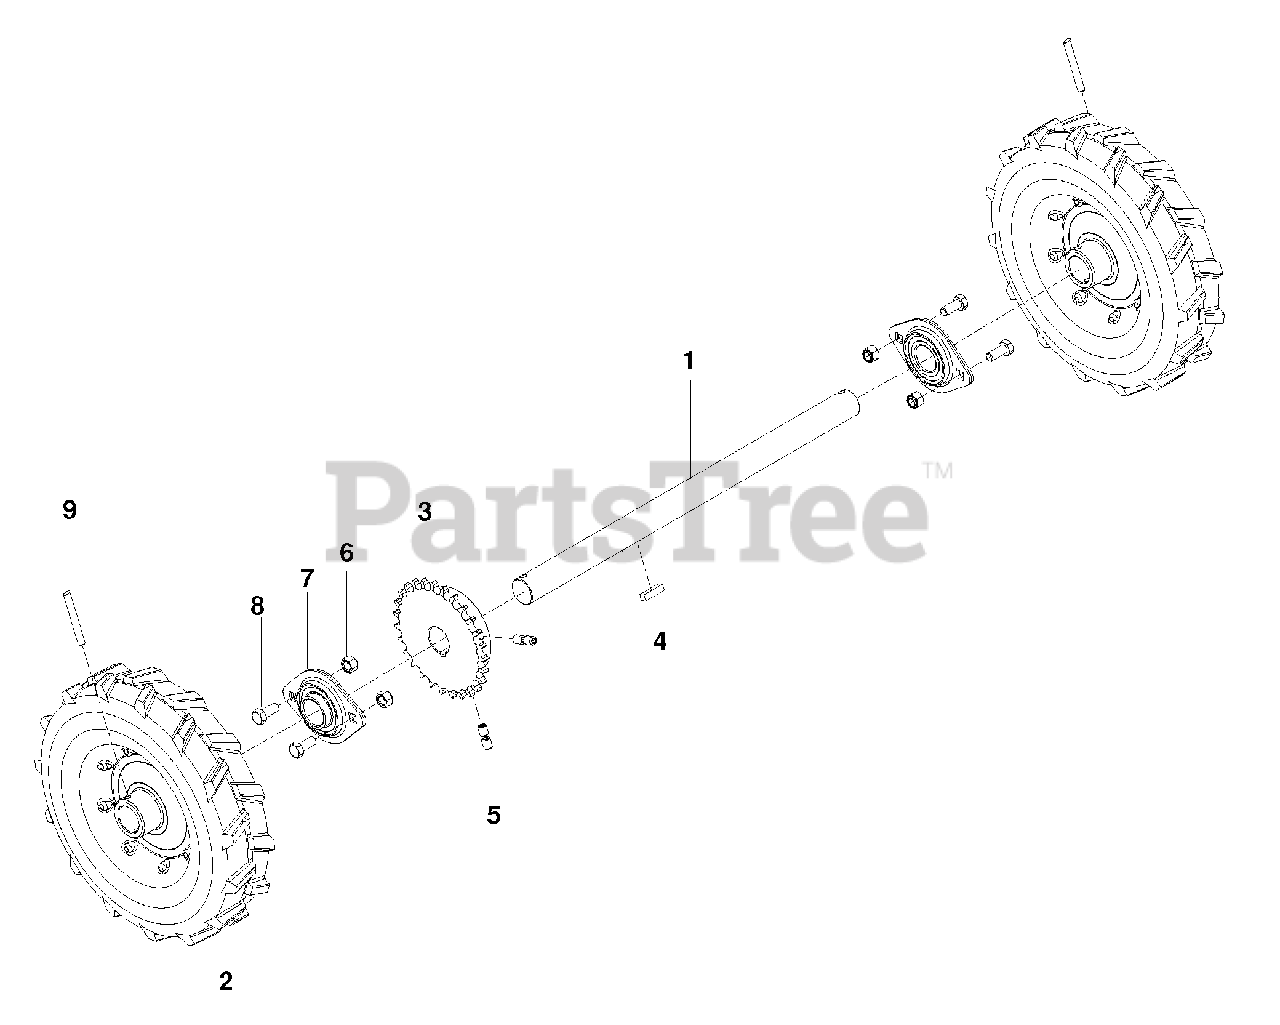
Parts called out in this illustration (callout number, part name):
2	WHEEL 2.75 x 10 x 1
4	KEY 1/4 SQ x 1
5	KPSS 5/16-18 x 3/8
6	NUT 5/16-18 NYLOC
7	BEARING FLANGE
8	HCS 5/16-18 x 3/4
9	SPIRAL PIN 1/4 x 1 1/2
